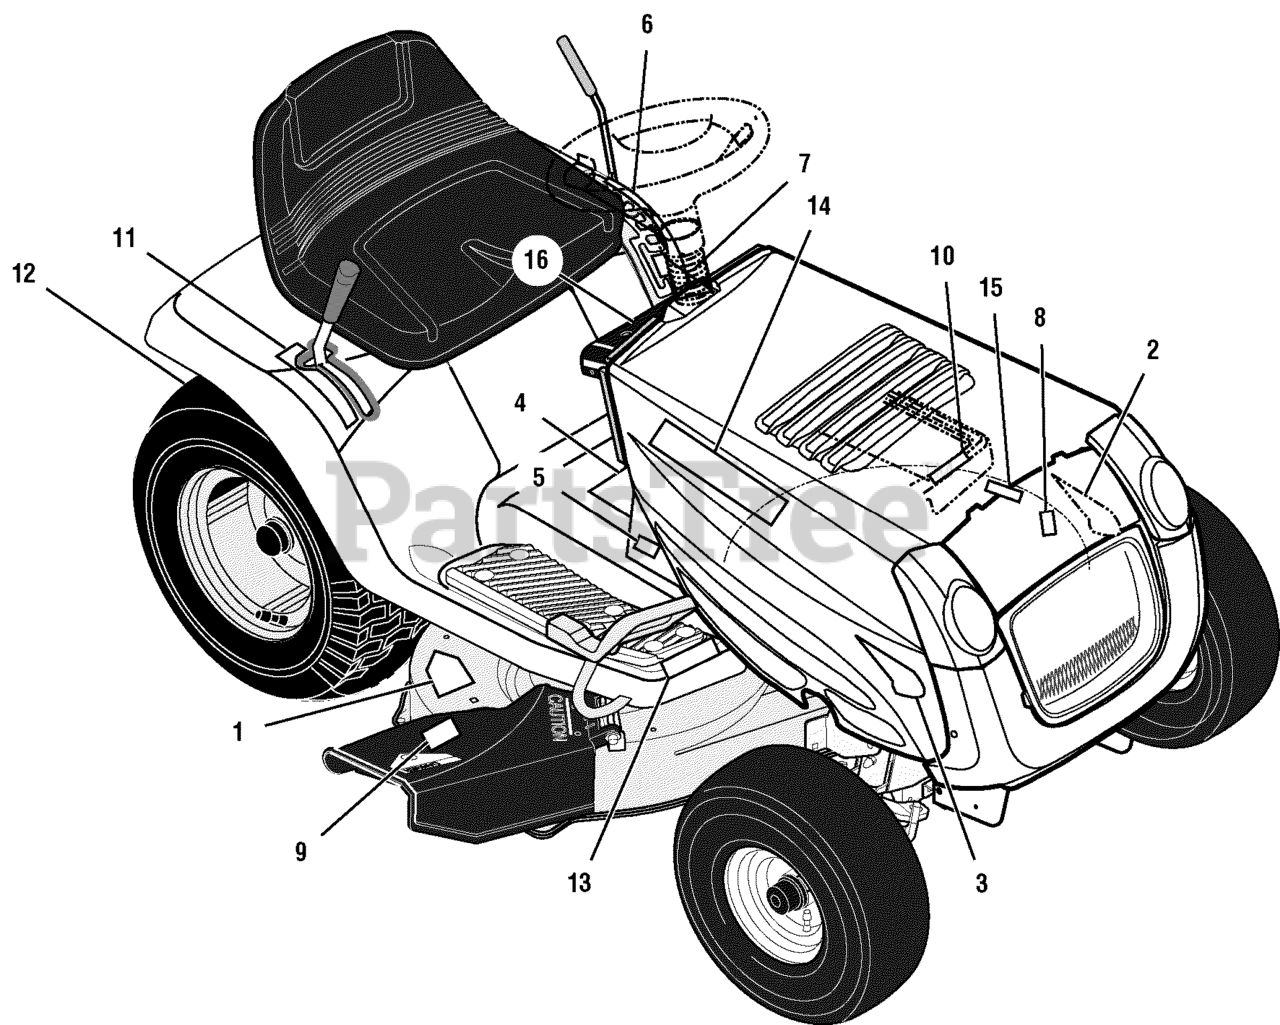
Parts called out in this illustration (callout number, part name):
1	DECAL, ENGLISH CUT FINGER
2	DECAL, 15.5/40 LH
3	DECAL, 15.5/40 RH
4	DECAL, WARNING
5	DECAL, BRIGGS LOGO
6	DECAL, 1/6 HGT ADJUST LIFT SMSD
7	DECAL, DECK LEVEL POS/ONLY
8	DECAL, NO STEP LH HSNG
9	DECAL, NO STEP CHUTE
10	DECAL, CLUTCH/BRAKE SILVER
11	DECAL, 6 SPD SM SD
12	DECAL, WARNING LOAD LMT
13	DECAL, V2-SS-1X3 CUTTING HGT
14	DECAL, SENTINEL BY MUR R & L
15	DECAL, 3 WAY
16	DECAL, IGNITION SWITCH (NMR)
